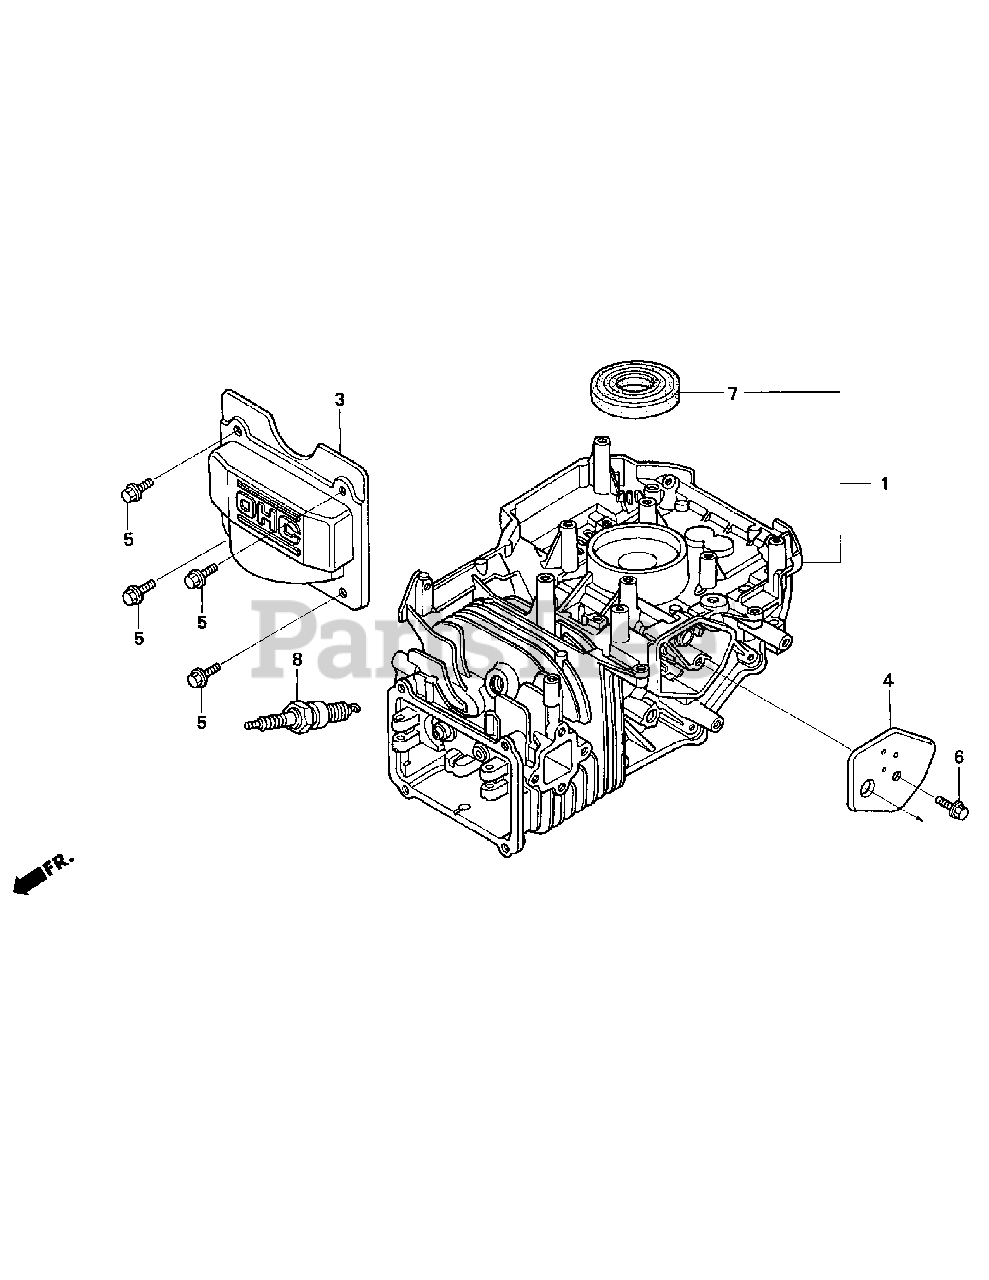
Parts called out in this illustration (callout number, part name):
1	CYLINDER ASSY. (010)
3	COVER, HEAD
4	COVER, BREATHER (BREATHER VALVE ASSY.)
5	BOLT, FLANGE (6X12) (CT200)
6	BOLT, FLANGE (6X14)
7	OIL SEAL (25.4X62X6)
8	SPARK PLUG (BPR6ES) (NGK)
